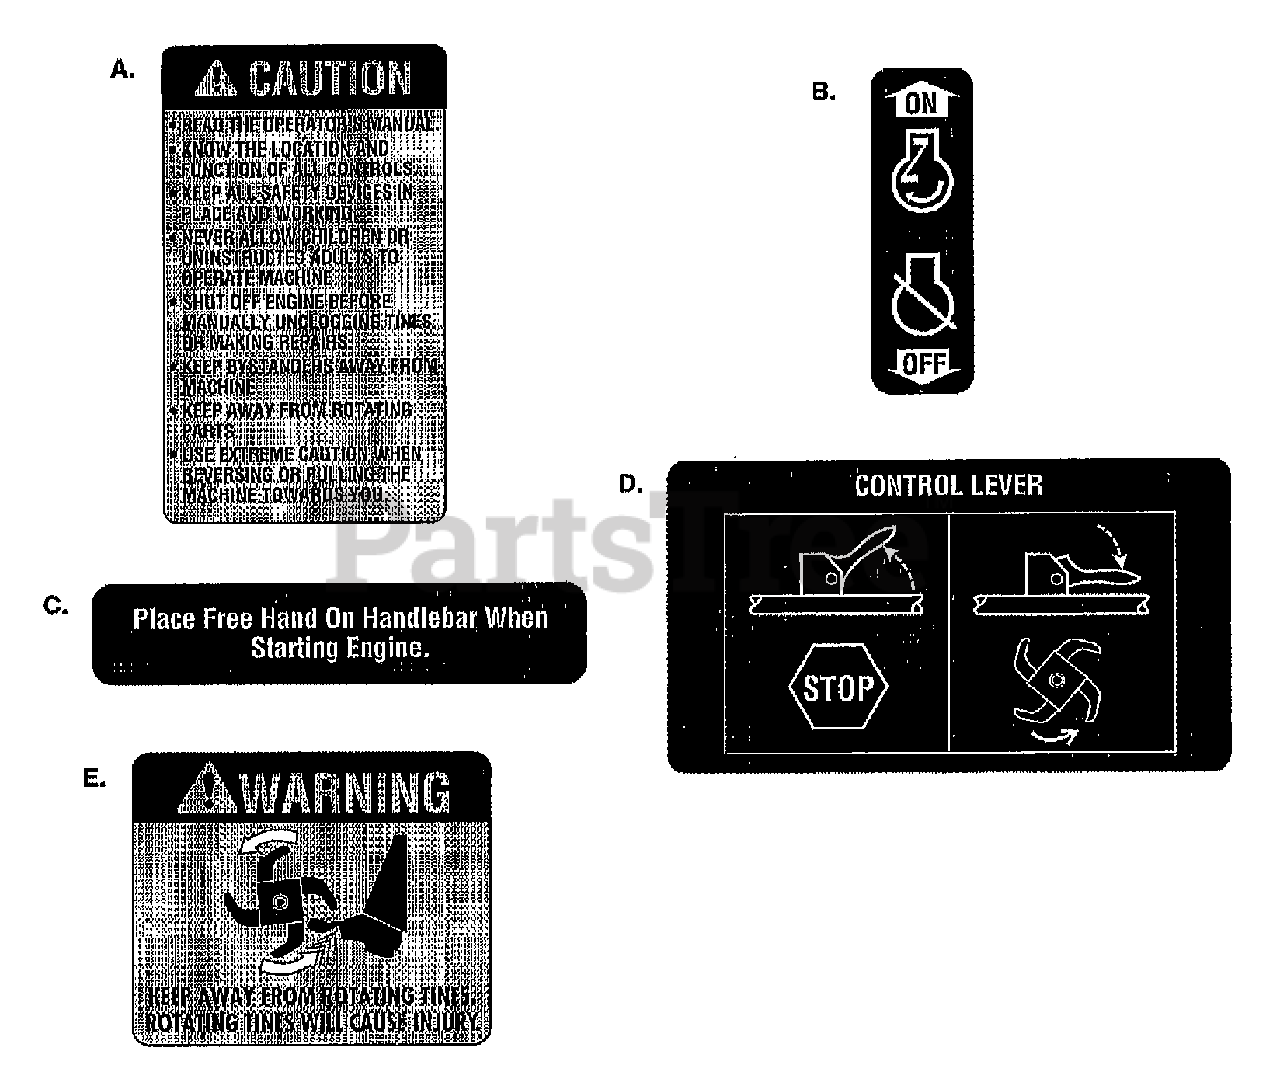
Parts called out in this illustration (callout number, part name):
A	DECAL-CAUTION ANSI SM TLR REAR OF HOOD
B	DECAL-OFF/ON (SM TLR) TOP OF HANDLEBARS
C	DECAL-STABILIZE/STARTING TOP OF HANDLEBARS
D	DECAL-CONTROL LEVER HANDLEBAR FOLD
E	DECAL-WARNING ANSI SM TLR REAR OF TINE HOOD
